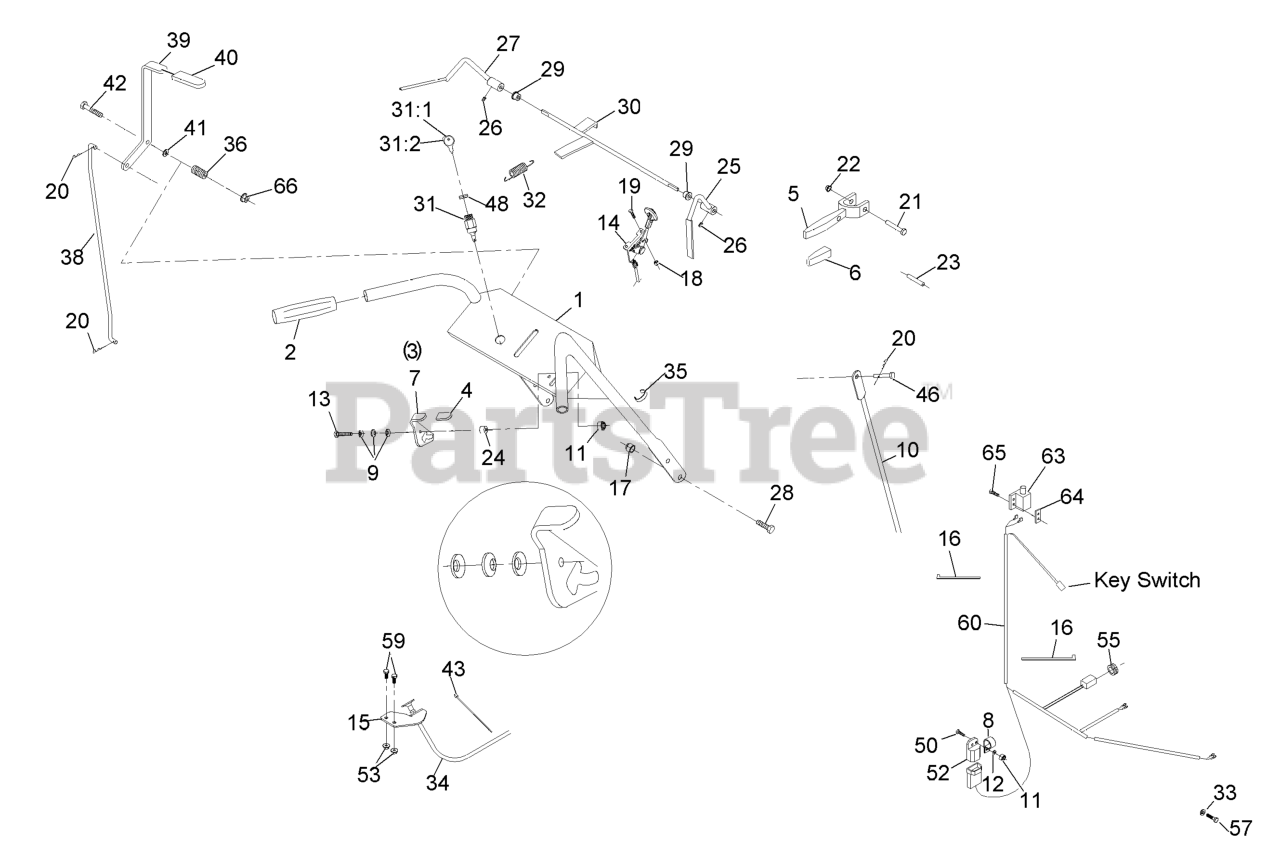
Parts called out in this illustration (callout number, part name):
1	KIT,HANDLE W/DECALS METRO
4	GRIP-LATCH
5	DRIVE LEVER ASM
6	GRIP-LEVER, DRIVE
8	CLIP-LOOM
9	WASHER-SPRING
10	LINKAGE-WHEEL, DRIVE
11	NUT-LOCK, NI
12	WASHER-FLAT
13	SCREW-HH
14	CONTROL, THROTTLE
15	BRACKET-CABLE, CHOKE
16	TIE-CABLE
17	NUT-LOCK, NI
18	NUT-LOCK, NI
19	BOLT-CARR
20	PIN-COTTER
21	PIN-LEVER, DRIVE
22	NUT-PUSH
23	PIN-ROLL
25	LEVER-RH
26	SCREW-SET
27	LEVER-LH
28	SCREW-HH
29	BUSHING-NYLON
30	WLD,ROD OPC
31	SWITCH & KEY (INCLUDES NU
31:1	KEYS-IGNITION (SPARE PAIR
31:2	KEY-IGNITION
32	SPRING-EXTENSION
33	WASHER-PLAIN
34	CABLE-CHOKE
35	CLIP-CABLE
36	SPRING-COMPRESSION
38	LINKAGE-BLADE, UPPER
39	LEVER ASM
40	GRIP-LEVER
41	WASHER-FLAT
42	SCREW-HH
43	TIE-PLASTIC
46	PIN-CLEVIS
48	NUT-SWITCH, IGNITION
50	SCREW-HH
52	MODULE-INTERLOCK
55	GROMMET
57	SCREW-HH
59	SCREW-HH
60	HARNESS-WIRE
63	SWITCH-OPEN, NORMALLY
64	PLATE-TAPPED
65	SCREW-PPH
66	NUT-HF, NI
